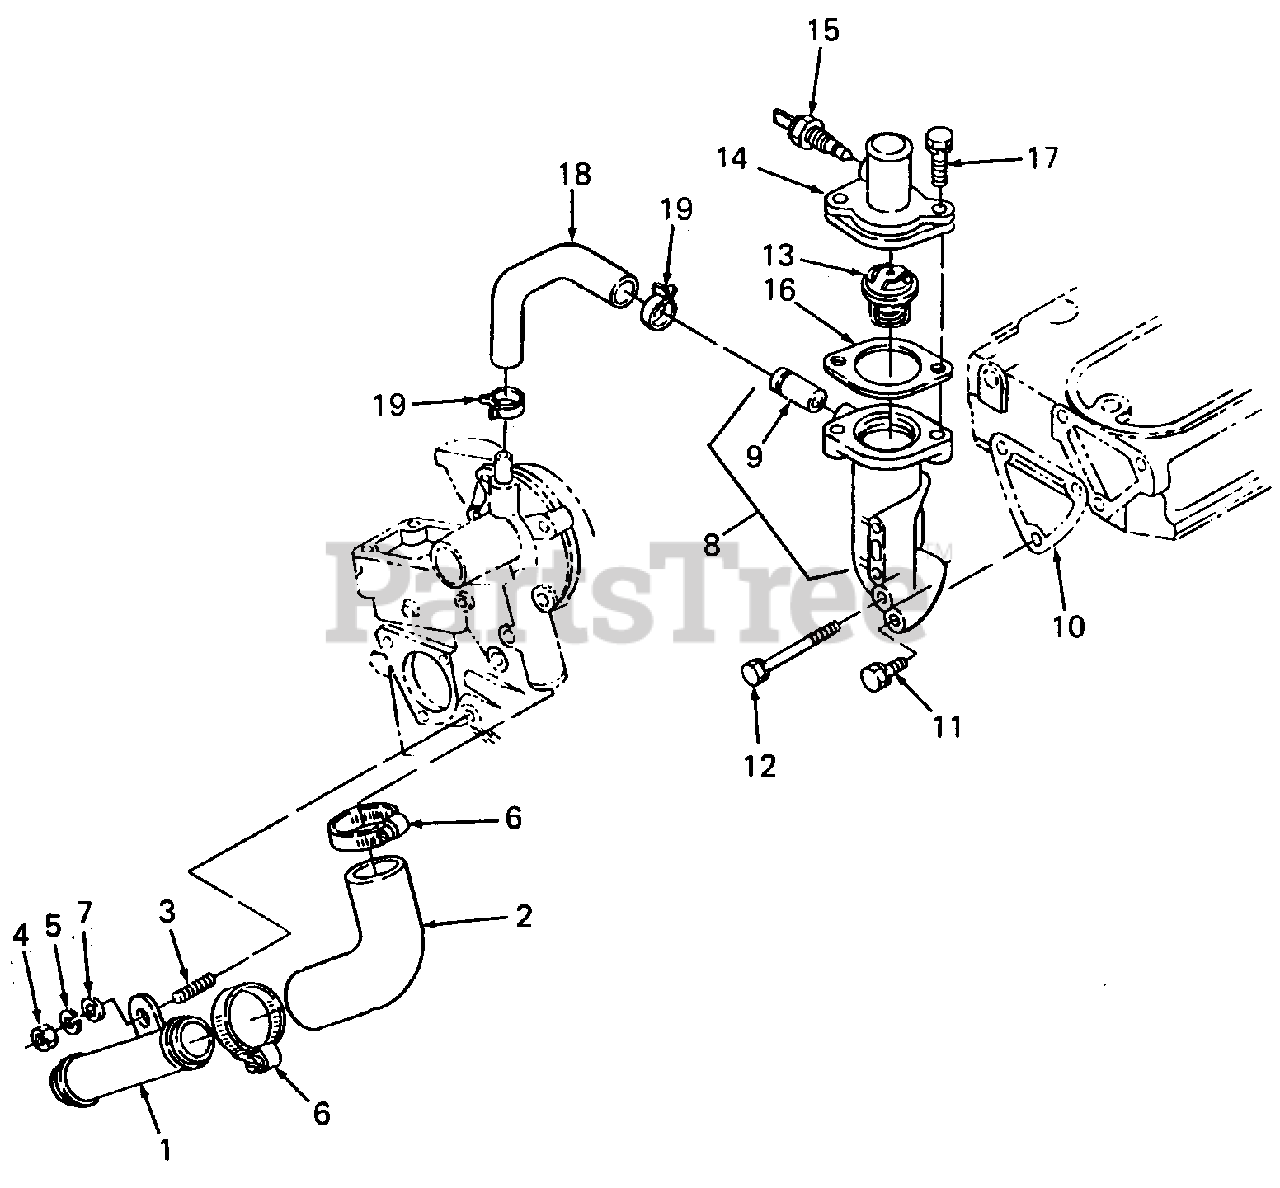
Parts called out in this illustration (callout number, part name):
5	Washer, Spring
7	Washer, Plain
8	Flange, Water
9	Pipe, Water Return
10	Gasket, Water Flange
13	Thermostat Assy
14	Cover, Thermostat
15	Thermoswitch
16	Gasket
18	Pipe, Water Return
